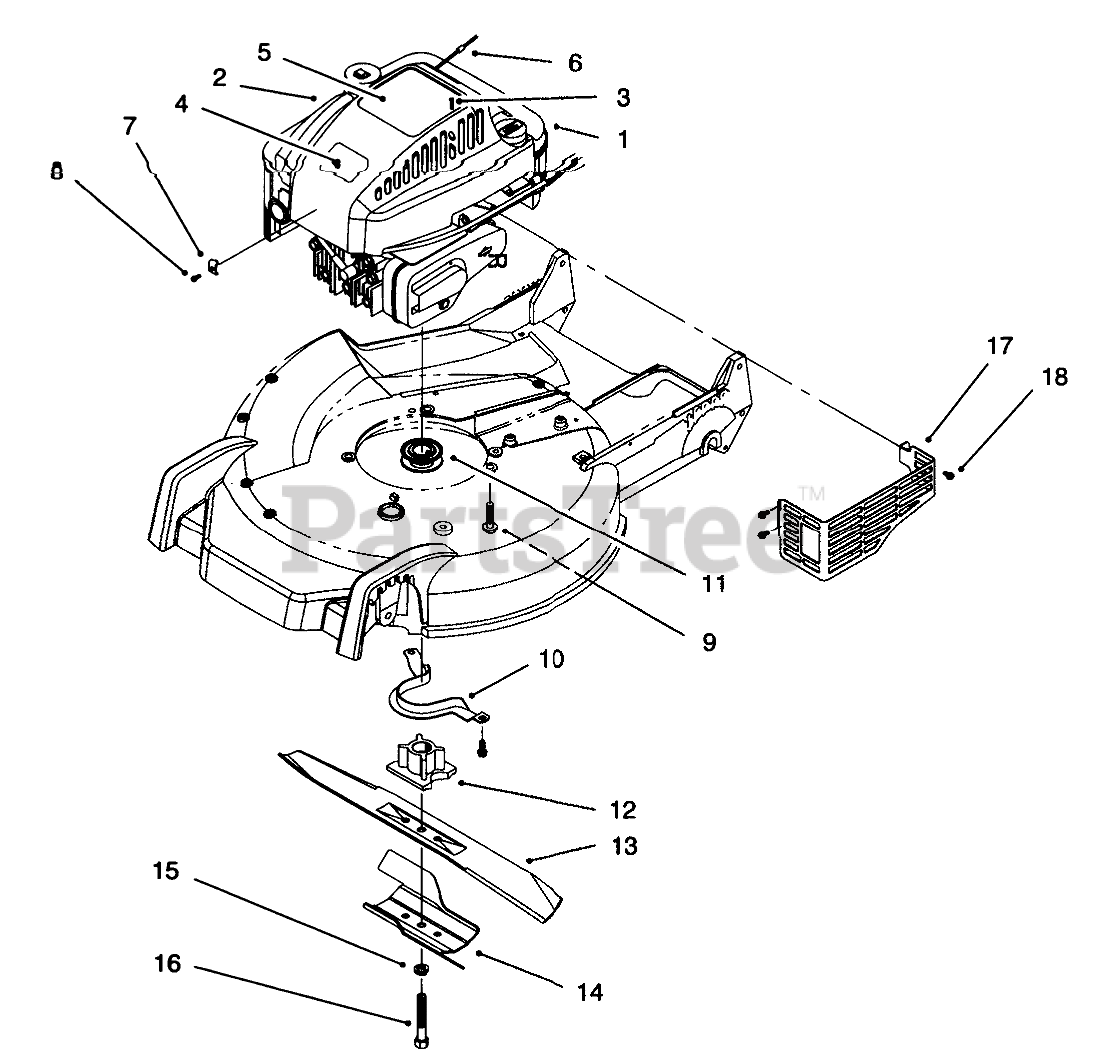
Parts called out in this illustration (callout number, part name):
1	Engine ASM
2	SHROUD-ENGINE
3	SCREW-PPH
4	PLATE-LOGO
5	DECAL - RECOIL
6	STOP-ROPE
7	CLAMP-CASING
8	SCREW-CLAMP
9	SCREW-HWH
10	Guide-Belt
11	PULLEY-DRIVE, ZONE START
12	RETAINER - BLADE
13	Blade
14	Stiffener-Blade
15	WASHER-LOCK
16	SCREW-BLADE
17	SHIELD-MUFFLER
18	SCREW-HWH
